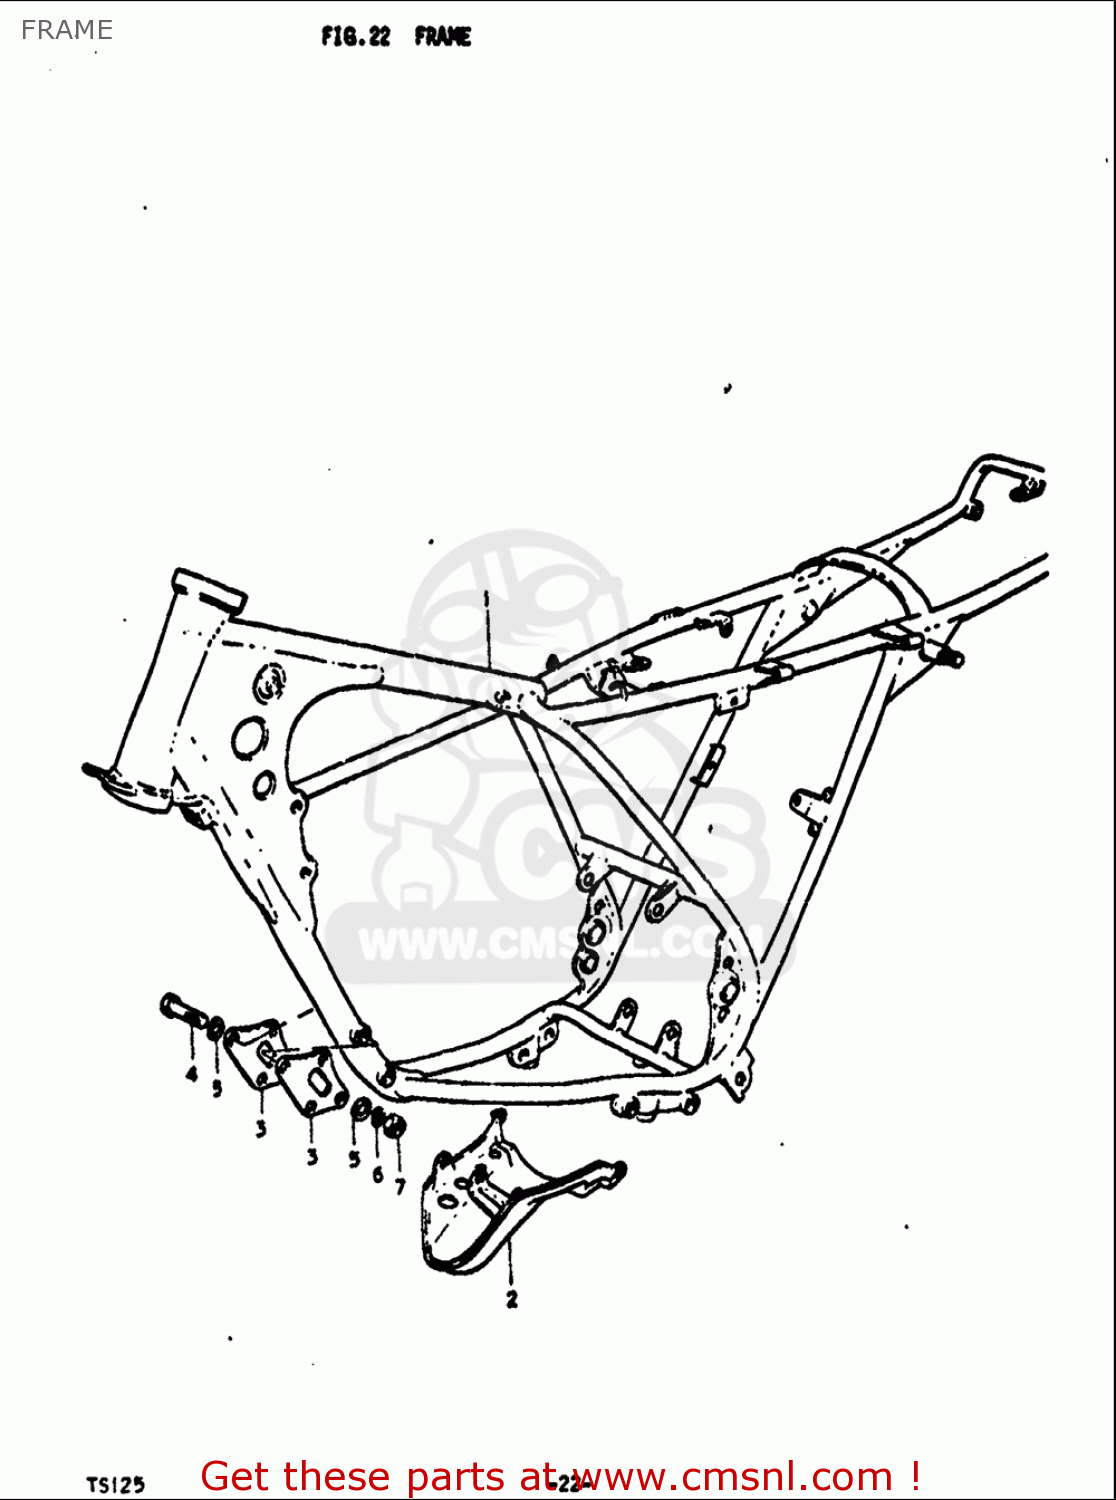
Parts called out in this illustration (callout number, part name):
4	BOLT(6X70)
5	WASHER
6	WASHER,LOCK
7	NUT
